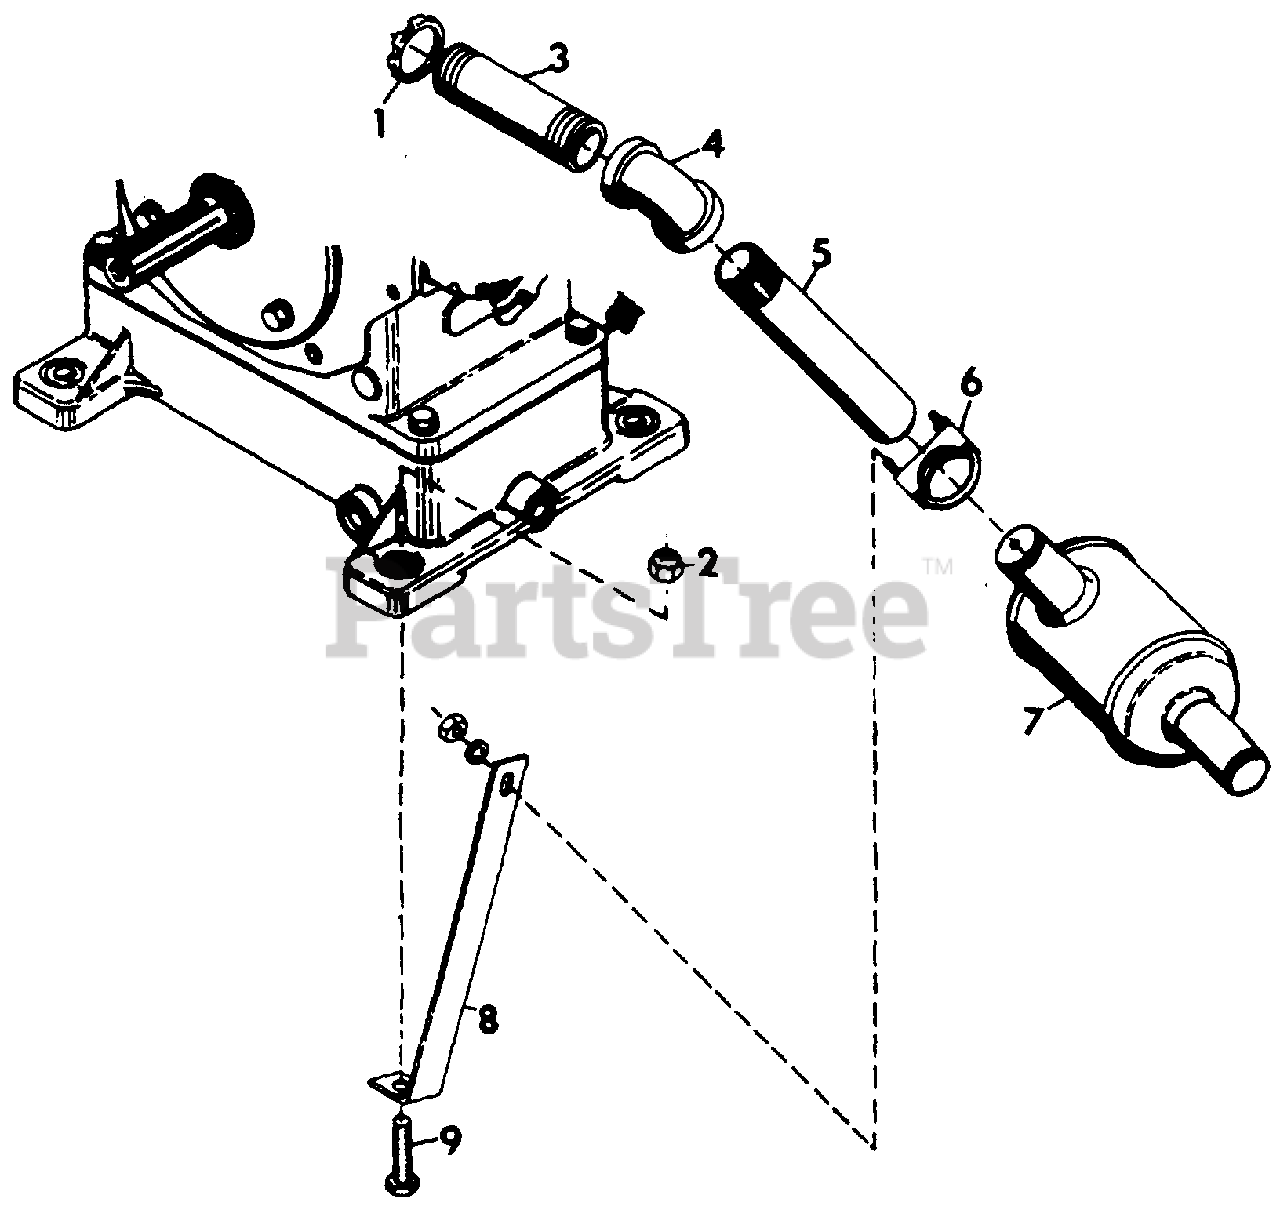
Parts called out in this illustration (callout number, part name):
1	NUT, CONDUIT 1" PIPE
2	NUT, LOCK 3/8-16
3	NIPPLE, PIPE 1X6
4	PIPE, 1" ELBOW
5	NIPPLE, PIPE 1X8.4 SPECIAL
6	CLAMP, MUFFLER
7	MUFFLER, EXHAUST
8	SUPPORT, EXHAUST
9	BOLT, HEX 3/8-16X1.25
